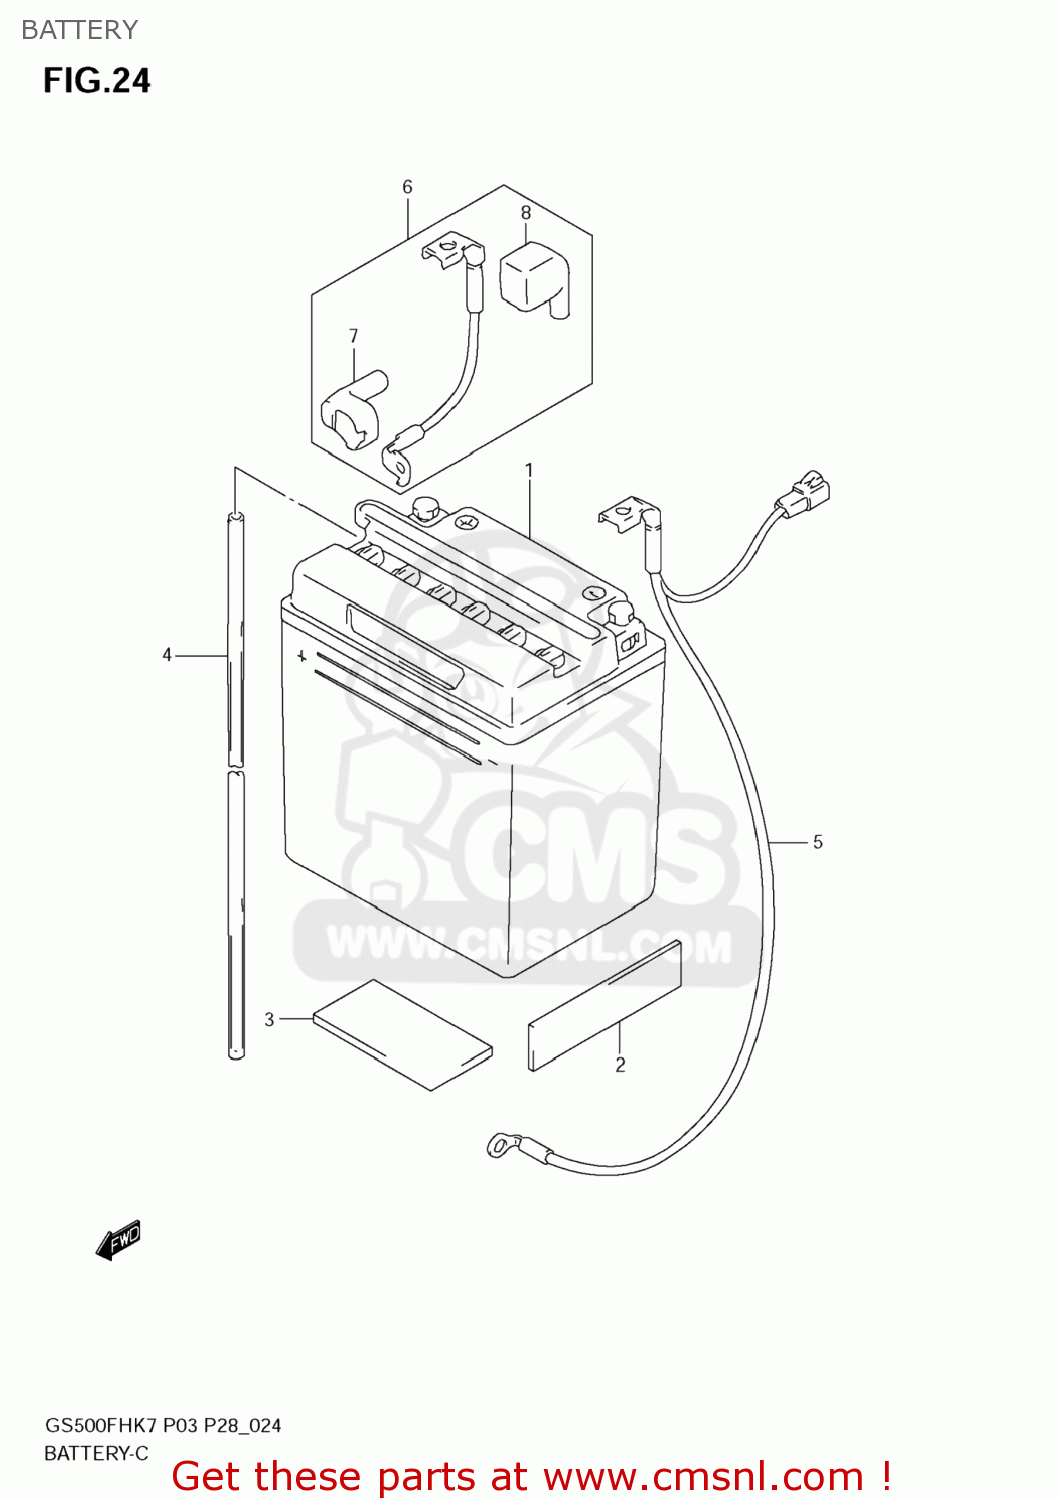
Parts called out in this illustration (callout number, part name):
1	BATTERY(YB10L-B2,12V11.6AH)
2	PROTECTOR (20X90X3)
3	CUSHION (40X75X5)
4	HOSE, EXHAUST
5	WIRE,BATTERY MINUS
6	LEAD WIRE,BATT
7	CAP,STARTER RELAY TERMINAL
8	CAP,BATTERY
